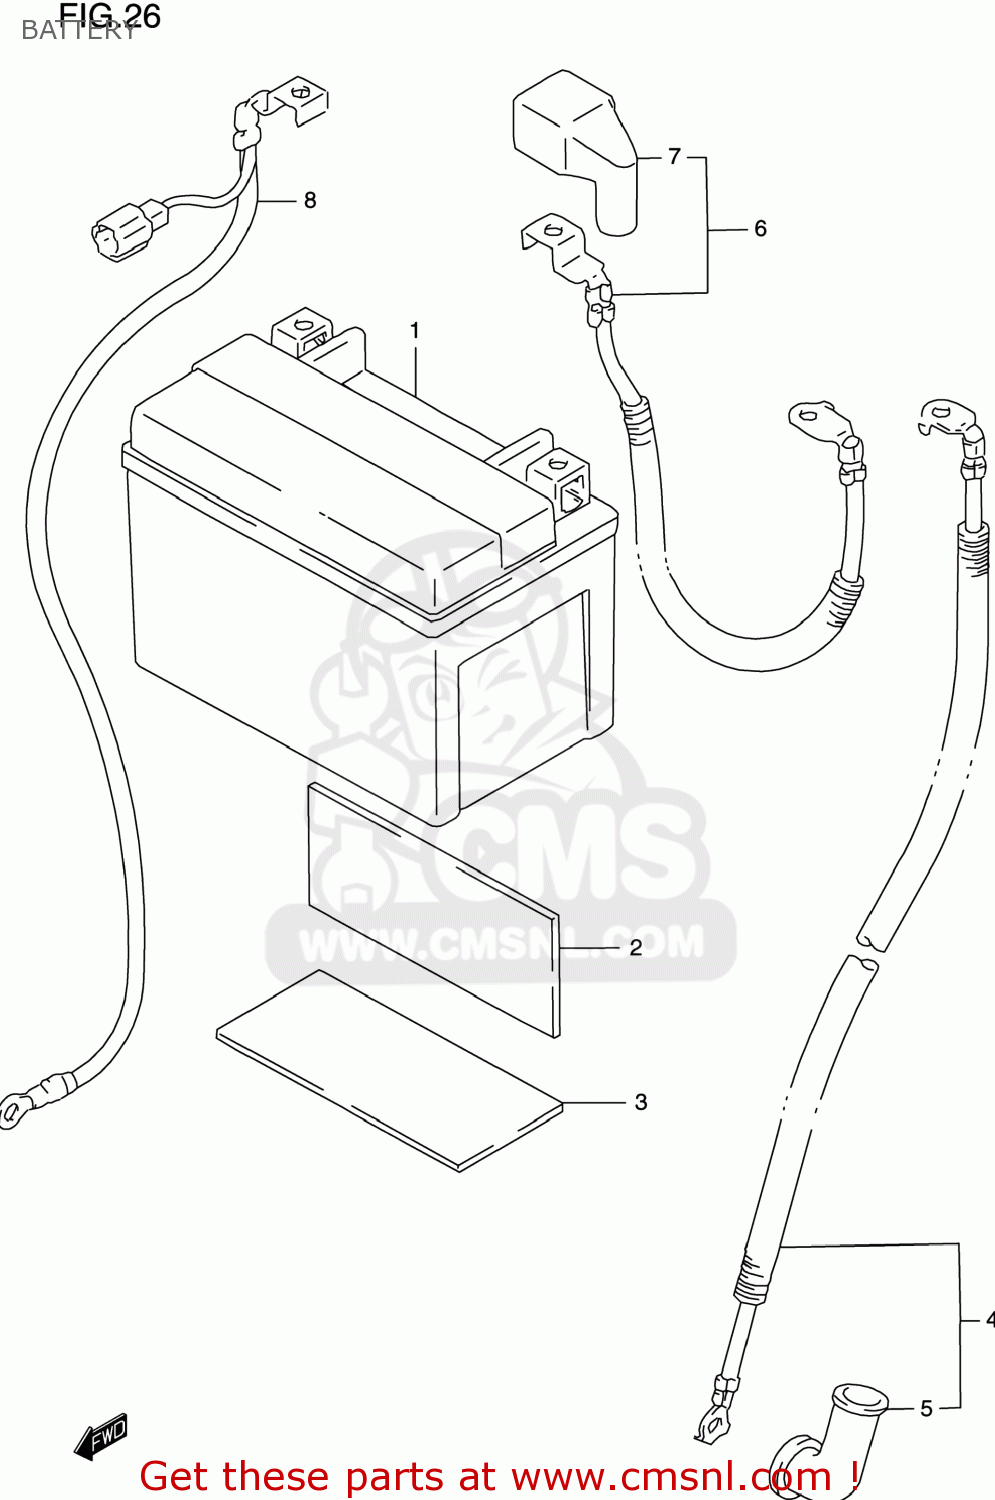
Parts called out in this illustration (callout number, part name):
1	BATTERY ASSEMBLY (12V) FTX
2	PROTECTOR(170X95X3.0)
3	CUSHION,BATTERY(90X45X18)
4	WIRE,STARTER MOTOR LEAD
5	CAP,STARTER MOTOR LEAD
6	WIRE,BATTERY PLUS LEAD
7	CAP,BATTERY PLUS TERMINAL
8	WIRE,BATTERY MINUS
